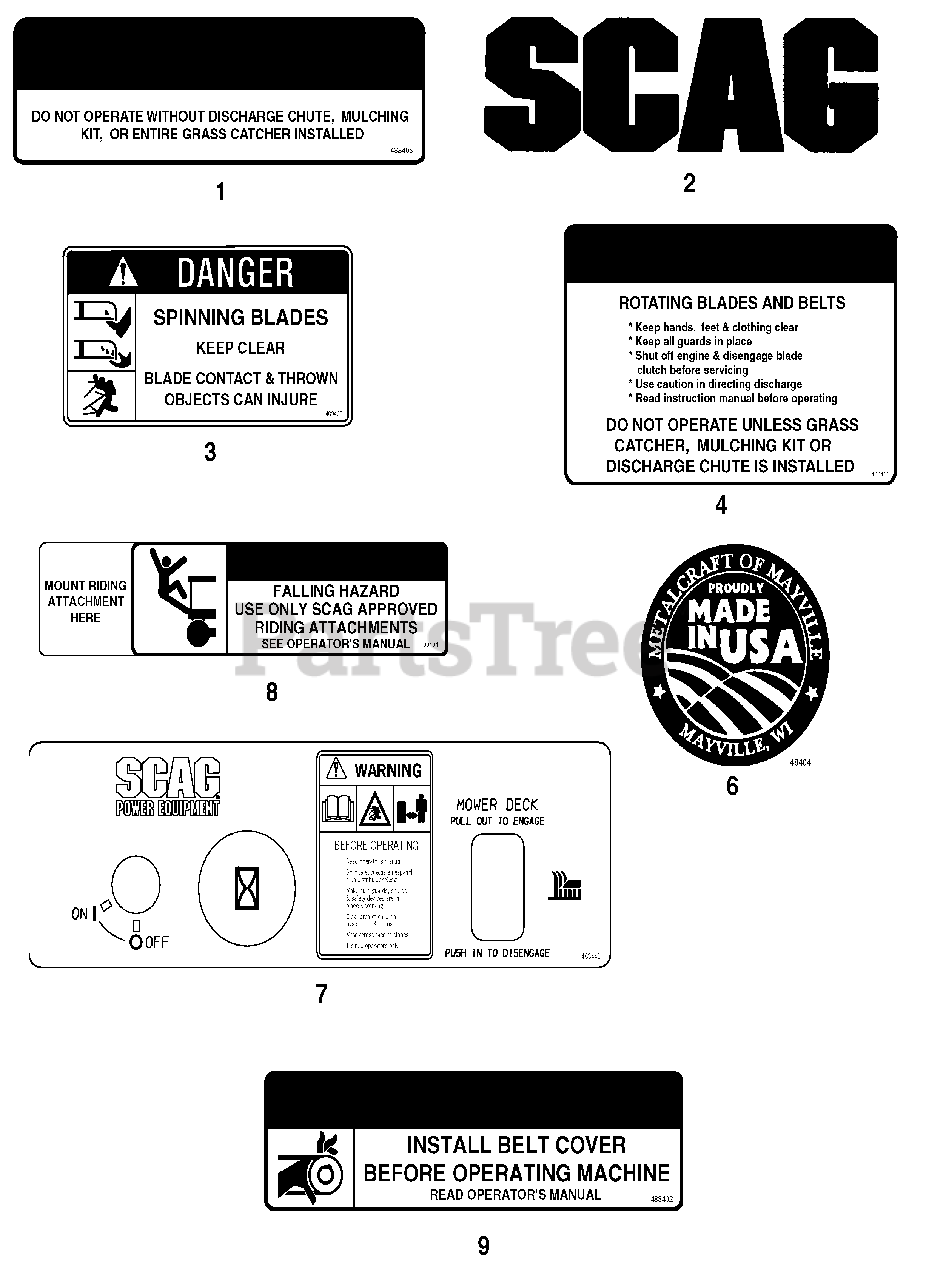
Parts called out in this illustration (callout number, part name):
1	Decal, Discharge Chute
2	Decal, Scag Logo
3	Decal, Danger-Spinning Blades
4	Decal, Warning-Rotating Blades
6	Decal, Metalcraft - Made in USA
7	Decal, Instrument Panel - Rear
8	Decal, Sulky Attachment
9	Decal, Belt Cover
